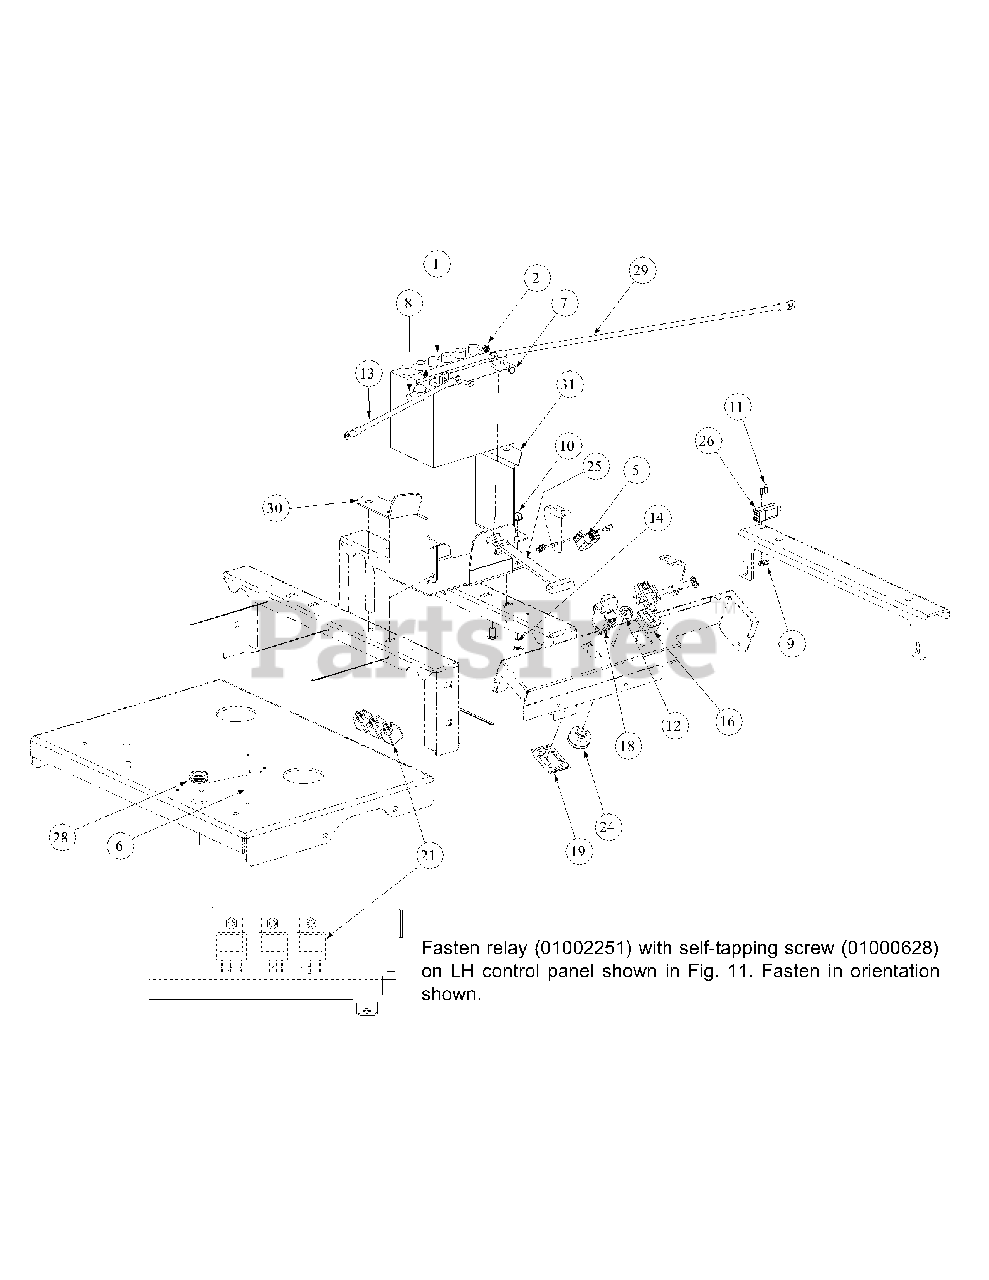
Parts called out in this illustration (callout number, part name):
1	Battery, 12V 225CCA 30 Min
2	Lock Nut, 1/4-20
5	Switch, Safety
6	Tie, Cable, 3/16 x .05 x 7.4"
7	Screw, Hex, Cap, 1/4-20 x .75
8	Boot, 1" OD Rubber Battery-PST, Red
9	Lock Nut, Nylon Insert
10	Nut, Hex, Flange Lock, 3/8-16
11	Screw, Phillips Head, Machine, 10-32 x 5/8
12	Nut, W/Cap, 5/8-32 Ignition
13	Cable, Battery, Red, 36"
14	Carriage Bolt, 3/8-16 x .75 LG.
16	Meter, Hour (Honda)
16	Meter, Hour (Kohler)
18	Switch, Electric, PTO
19	Bracket, PTO Switch Retainer
21	Relay, 12V 40A
24	Switch, Ignition, 6 Pin
24	Key, Ignition
25	Strap, Battery
26	Switch, Plunger
28	Grommet, .75 ID
29	Cable, Battery Red, 24"
30	Mount Bracket, Battery
31	Mount Bracket, Battery
